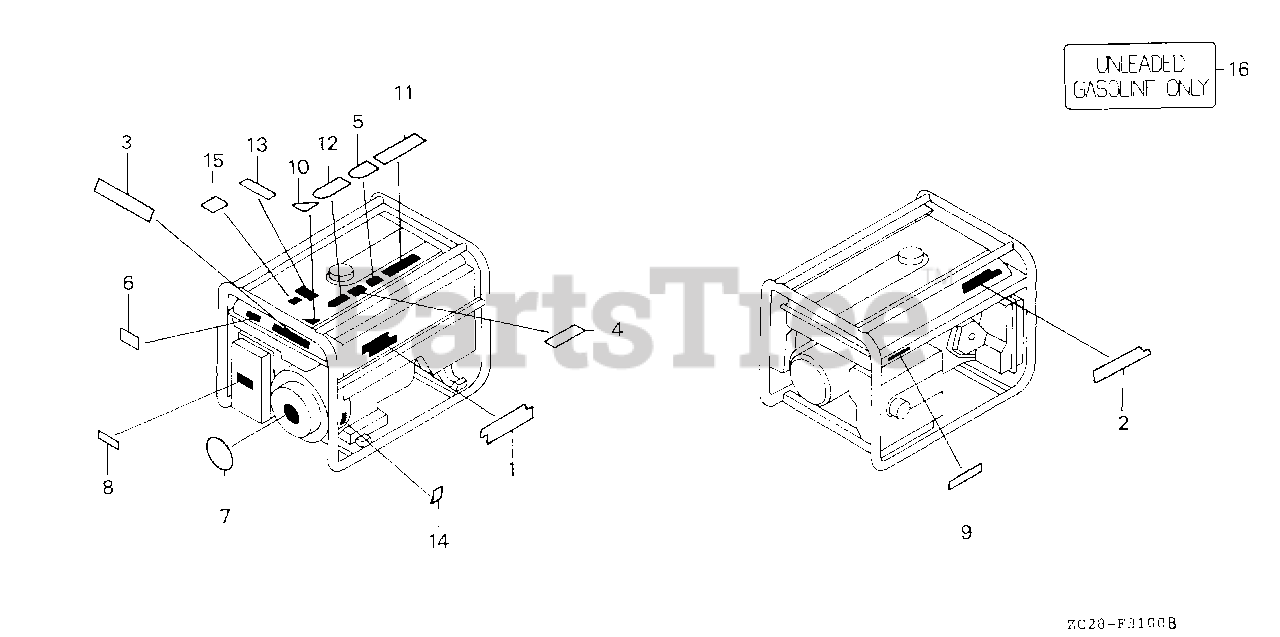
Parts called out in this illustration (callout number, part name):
1	MARK, EMBLEM (EW)
2	MARK, HONDA
3	PLATE, CAUTION
4	LABEL, RAIN WARNING (ENGLISH)
5	MARK, CAUTION (ENGLISH/FRENCH)(SPANISH)
6	MARK, CHOKE
7	MARK, OIL ALERT
8	MARK, AIR CLEANER
9	MARK, EX. CAUTION (ENGLISH/FRENCH)
10	LABEL, RENTAL USE (E)
11	MARK, CAUTION (CO)(ENGLISH/FRENCH)(SPANISH)
12	LABEL, CONNECT WARNING (ENGLISH)
13	MARK, FUEL METER
14	MARK, OIL CAUTION
